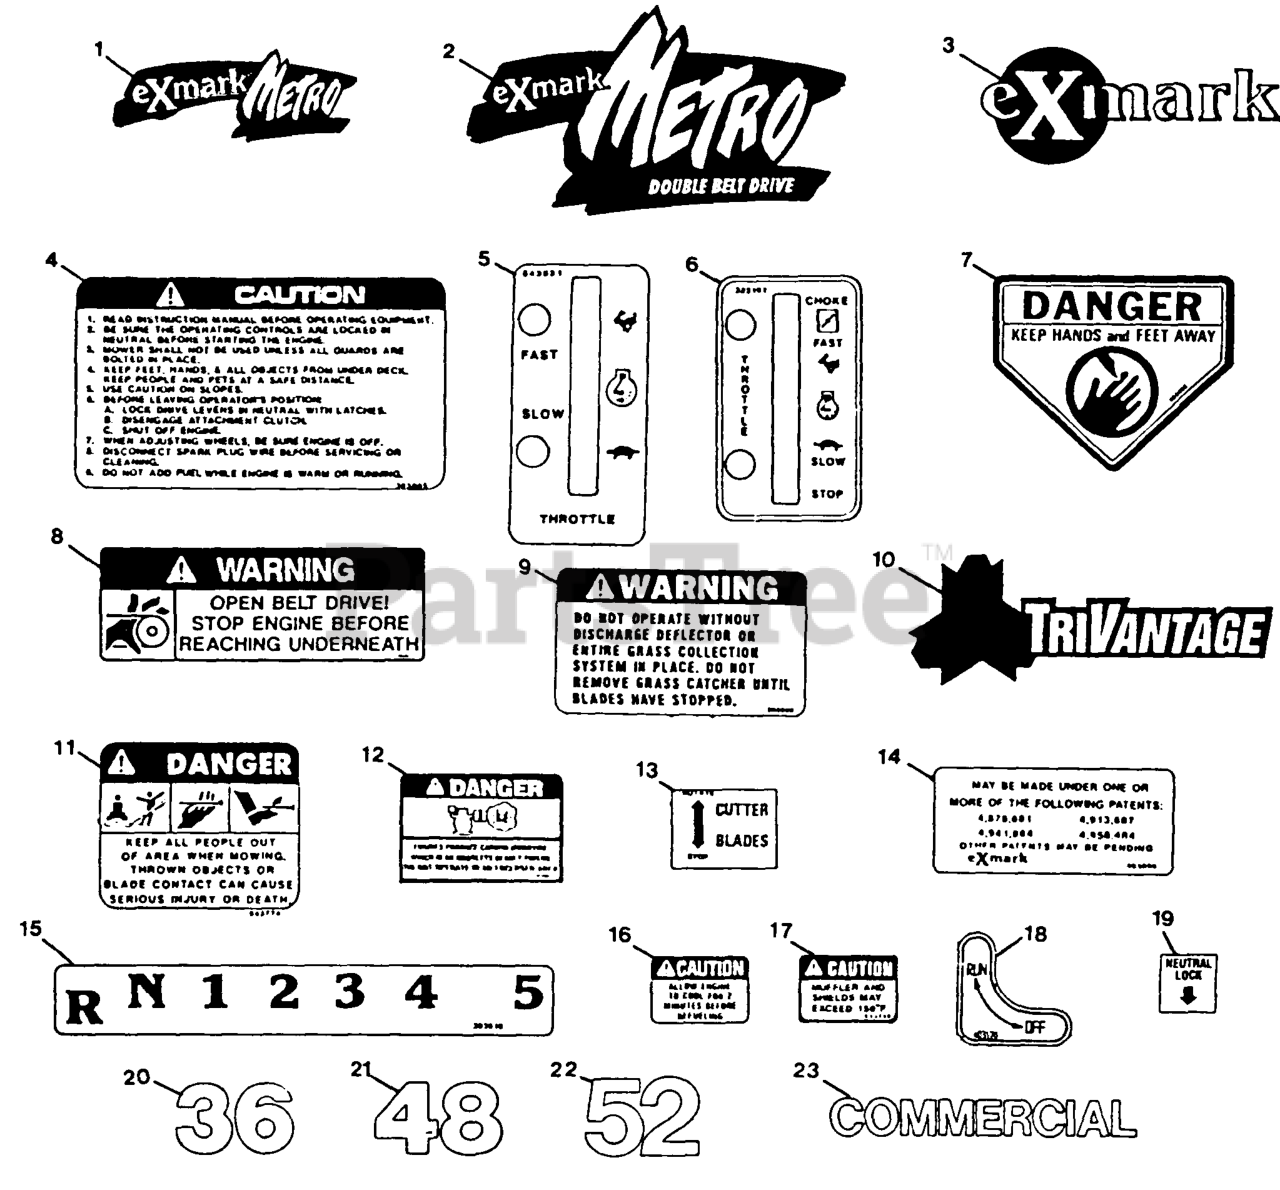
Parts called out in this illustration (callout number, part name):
4	LABEL,INSTRUCTION
7	DECAL-DANGER
8	DECAL,BELT DRIVE
9	DECAL-WARNING, DISCHARGE
11	DECAL-DANGER
13	DECAL,CUTTER BLADE
15	DECAL,SHIFTER
19	DECAL,NEUTRAL LOCK
